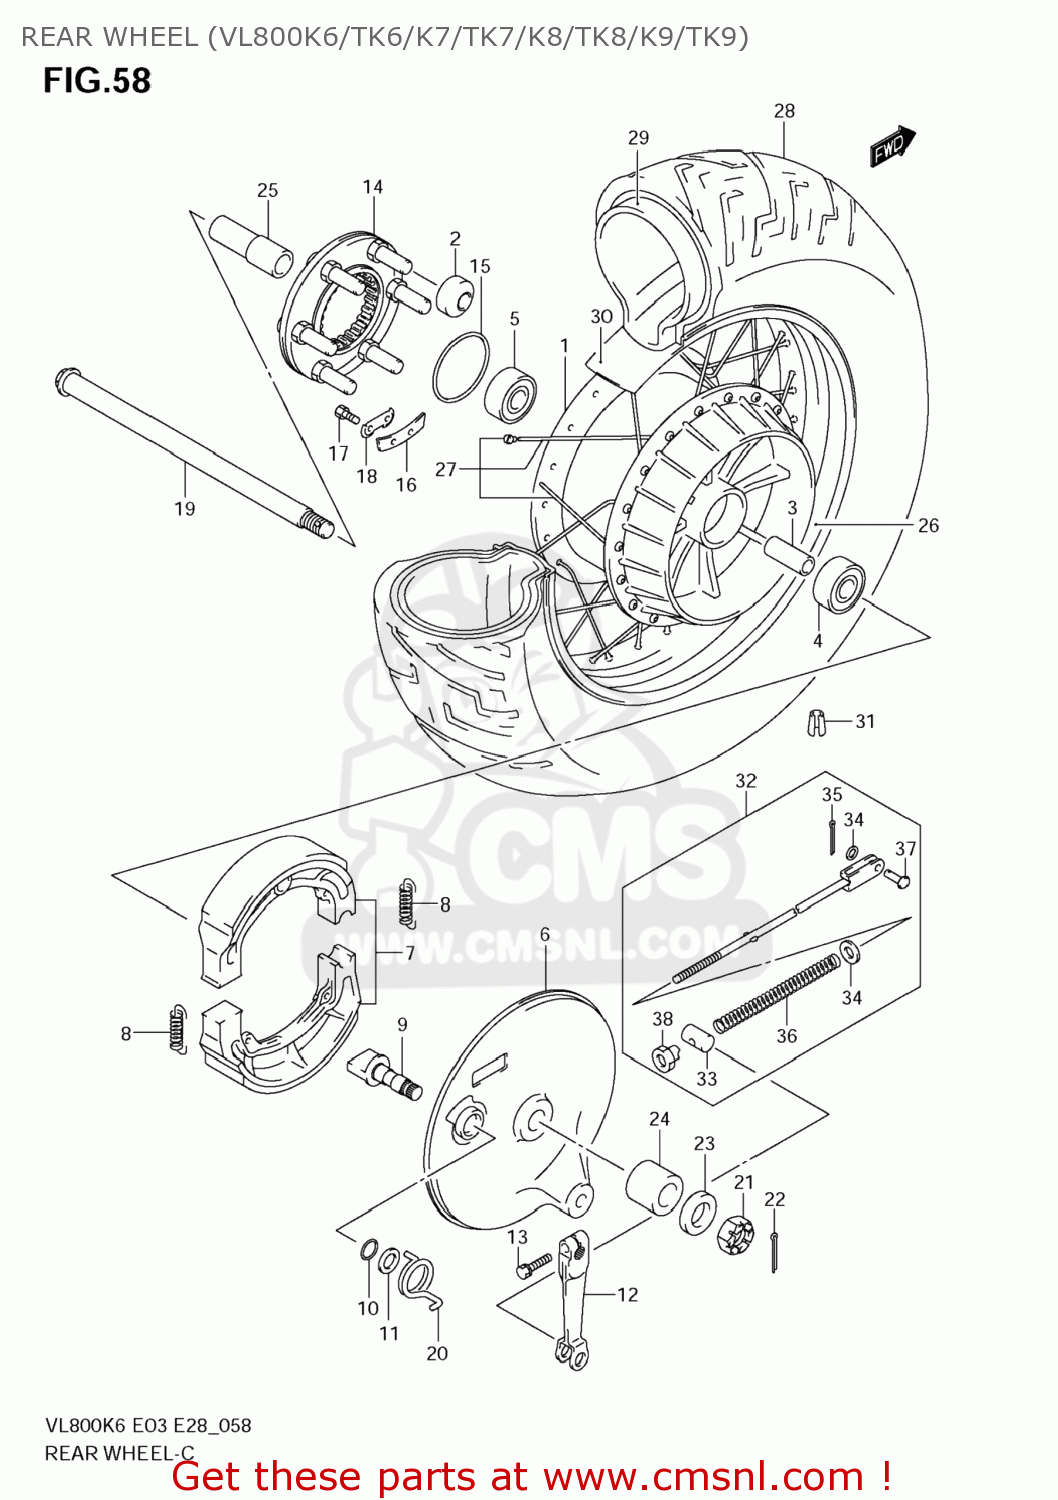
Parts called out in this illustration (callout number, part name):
1	HUB,RR WHEEL
2	BUSH
3	SPACER(17.5X25X113)
4	BEARING
5	BEARING
6	PANEL, REAR BRAKE ANCHOR
7	SHOE SET,BRAKE (NAS)
8	SPRING,BRAKE SHOE
9	CAM,RR BRAKE
10	O RING(D:2.4,ID:14.8)
11	WASHER(15.5X24X1.6)
12	LEVER,RR BRAKE CAM
13	BOLT
14	JOINT ASSY,RR HUB DRIVEN
15	O RING(D:2.1,ID:65)
16	WASHER,THRUST(T:1.6)
17	BOLT(6X16)
18	WASHER
19	AXLE,RR
20	SPRING
21	NUT
22	PIN
23	WASHER(17X30X3.2)
24	SPACER,RR AXLE,R
25	SPACER,RR AXLE,L
26	RIM,RR WHEEL(15M/CXMT4.00 FE)
27	SPOKE SET,RR WHEEL
28	TIRE(170/80 15M/C 77H)
29	TUBE ASSY,WHEEL INNER
30	PROTECTOR,WHL INR TUBE
31	BALANCER,WHEEL(15G)
32	ROD ASSY,RR BRAKE
33	PIN(13X18)
34	WASHER
35	PIN
36	SPRING
37	PIN(L:13.5)
38	NUT
